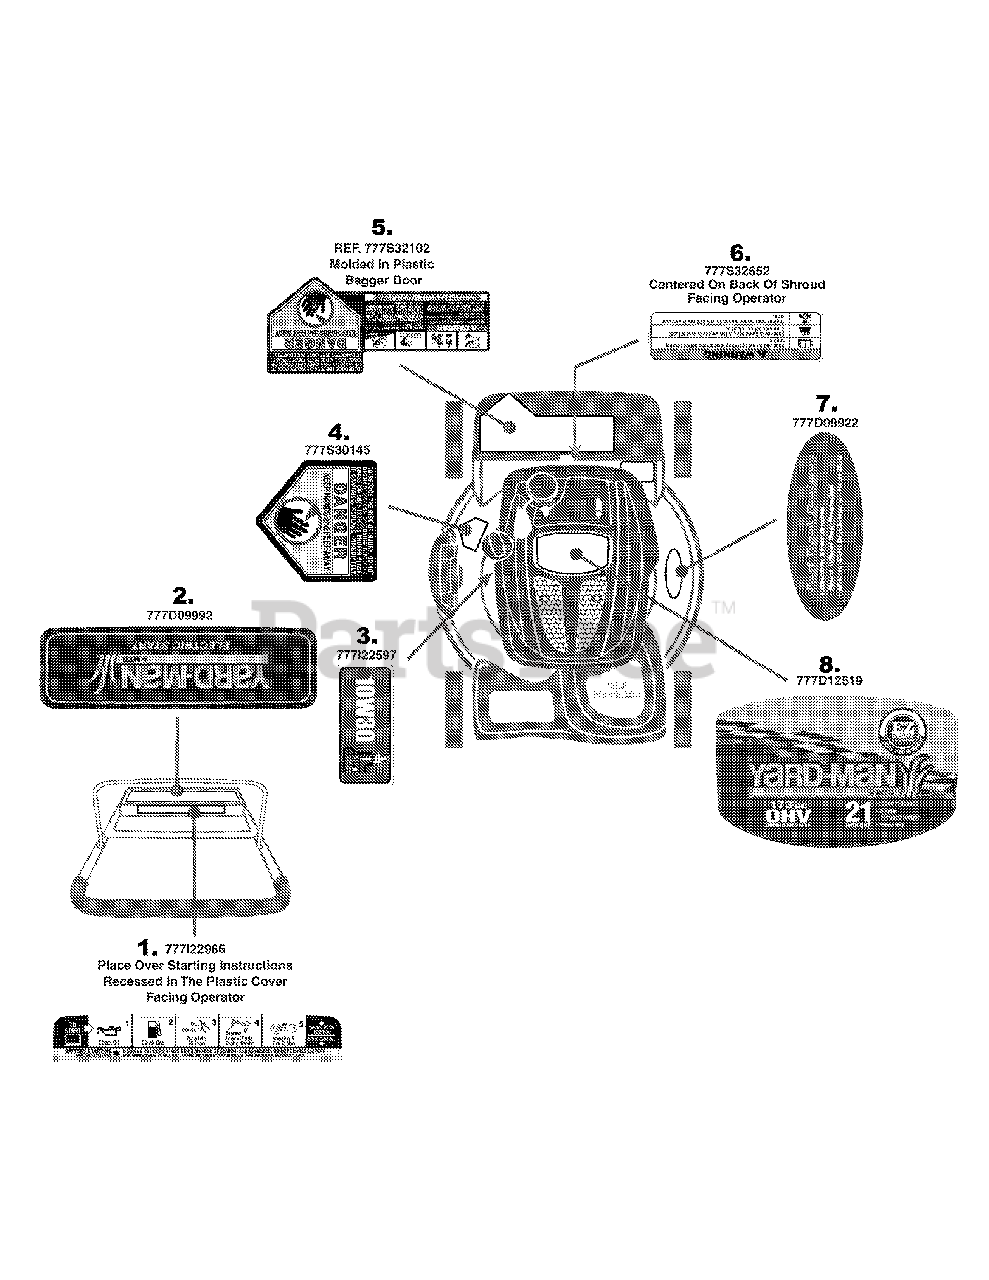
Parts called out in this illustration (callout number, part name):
1	LABEL-MOWER BATTERY PACK
2	LABEL-MOWER HANDLE YARD MAN ELEC
3	LABEL:MOWER SHROUD
4	LABEL
5	LABEL
6	LABEL:MOWER:ENGINE SHROUD
7	LABEL-MOWER DECK YARD MAN FAST TRK
8	LABEL-MOWER SHROUD YARDMAN 21"
